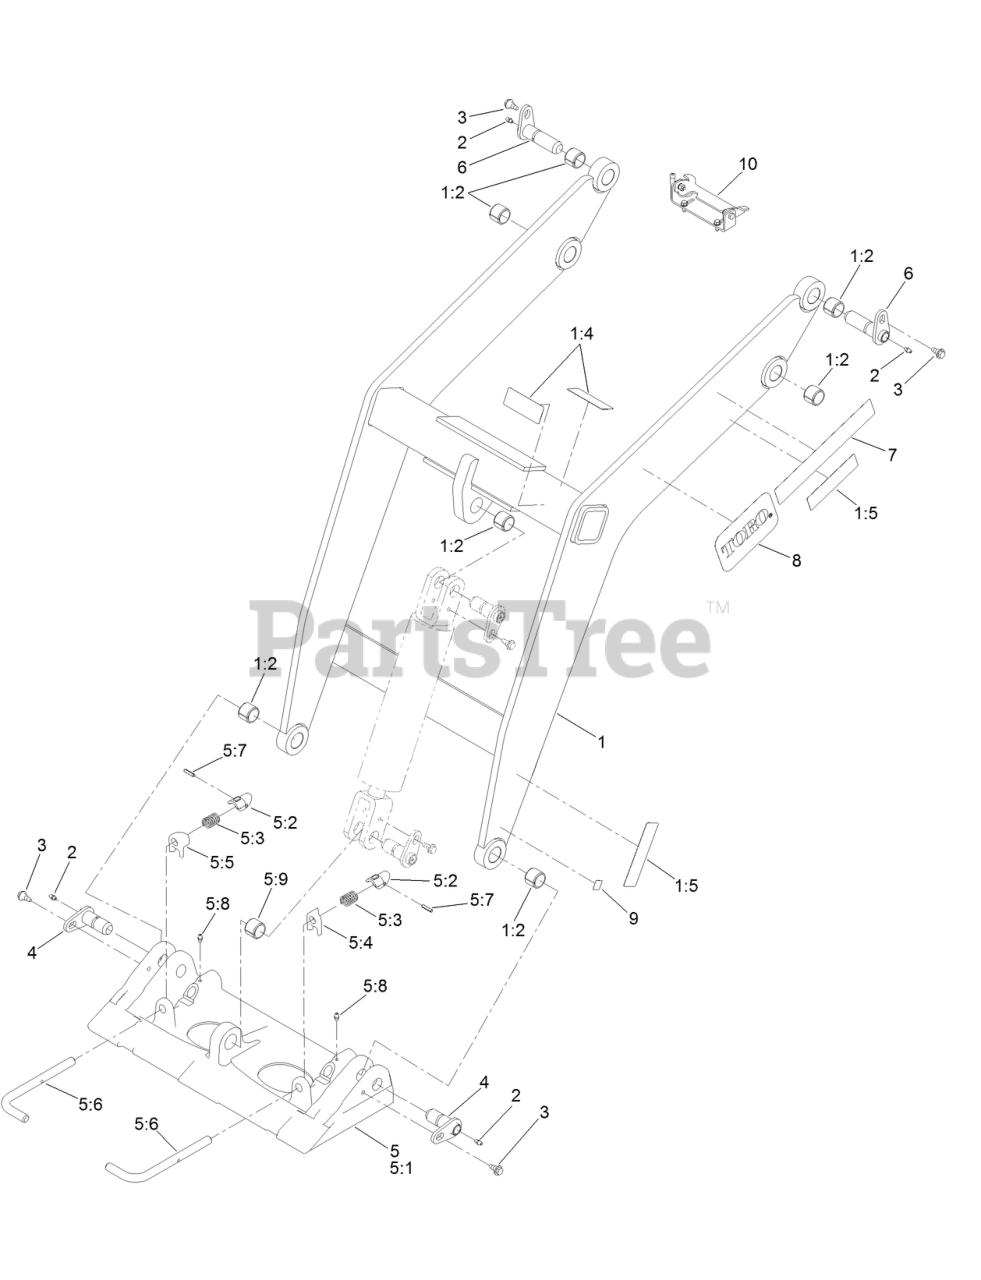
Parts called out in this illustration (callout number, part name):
1	LOADER ASM
1:2	BUSHING-TENSION
1:4	DECAL-WARNING, CRUSHING
1:5	DECAL-WARNING, NO RIDER
2	FITTING-GREASE
3	BOLT-SHOULDER
4	PIN-PIVOT
5	QUICK ATTACH ASM
5:1	MOUNT-QTACH
5:3	SPRING-COMPRESSION
5:4	STOP-RH
5:5	STOP-LH
5:6	PIN-LOCKING
5:7	PIN-GROOVED
5:8	FITTING-GREASE
5:9	BUSHING-TENSION
6	PIN-PIVOT
8	DECAL
9	DECAL-POINT, LIFT
10	LEVER LOCK ASM
